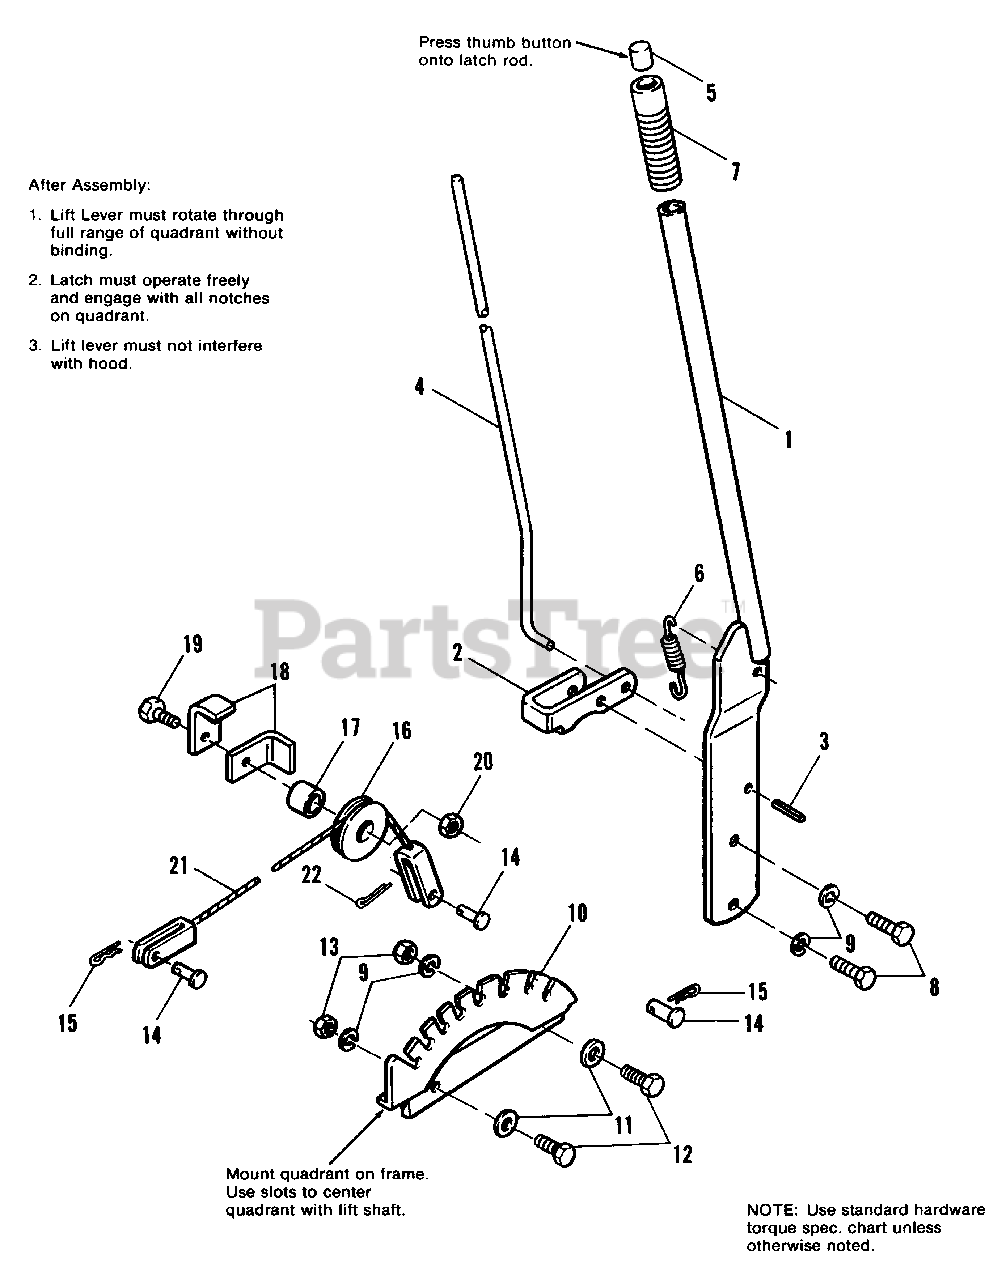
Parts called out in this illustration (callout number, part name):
1	LIFT LEVER ASSEMBLY
2	LATCH, Lift Lever
3	PIN, Spring, 3/8 x 1-1 /4
4	ROD, Latch
7	GRIP
8	CAPSCREW, Hex Hd., 3/8-16 x 1
9	LOCKWASHER, 3/8
11	WASHER, 5/16
12	CAPSCREW, Hex Hd., 3/8-16 x 7/8
13	NUT, Hex, Full, 3/8-16
15	CLIP, Spring
18	GUARD, Cable
19	SCREW, Special
20	LOCKNUT, Hex, Jam, 3/8-16
21	LIFT CABLE ASSY.
22	PIN, Cotter, 3/32 x 7/8
